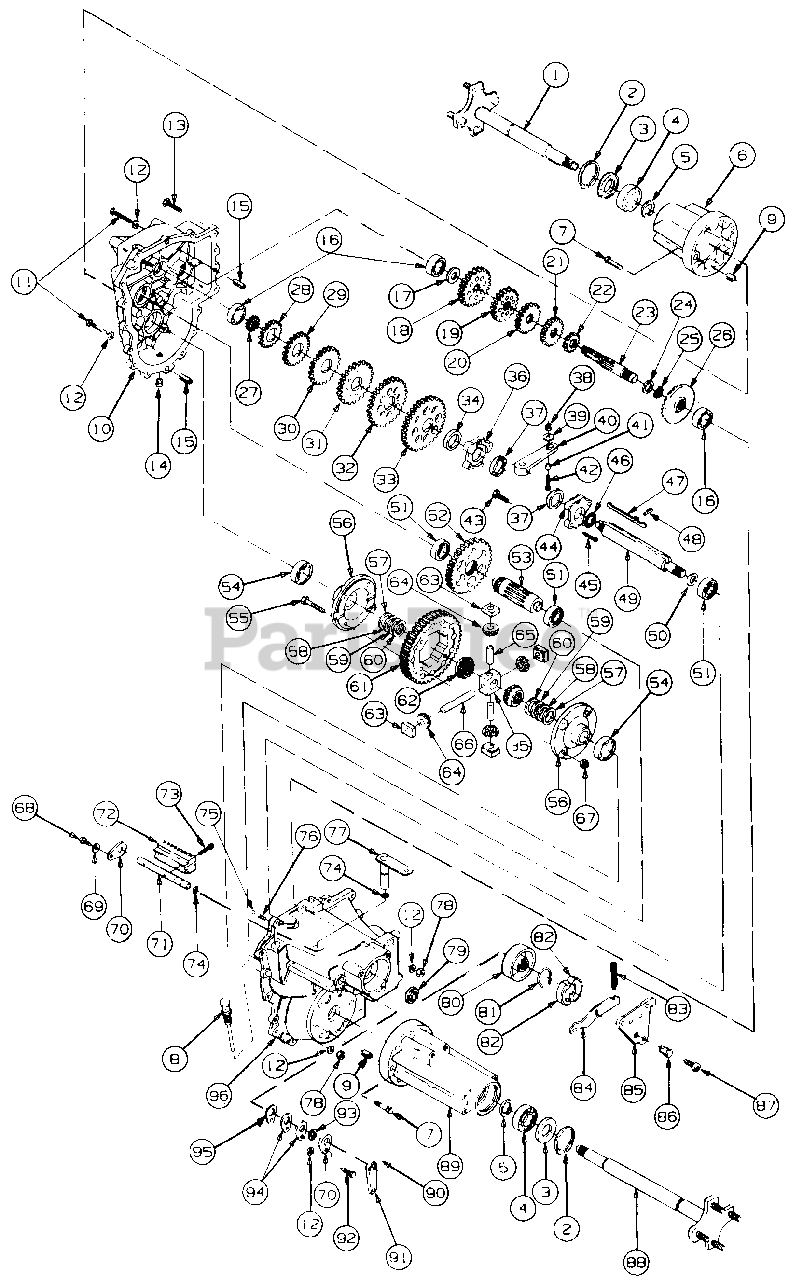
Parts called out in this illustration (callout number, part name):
1	Axle Assy, LH, 11.9" Lg
2	Ring, Inverted Retainer
3	Seal, Oil
4	Bearing
5	Ring, External Retaining
6	Housing, LH Axle
7	Crew, Hex L-Wash Tapp, 3/8-16 x 1.88
8	Dipstick, Oil
9	Bushing, Dowel
10	Housing, LH Differential
11	Screw, Hex Cap, 1/4-20 x 1.5
12	Washer, Flat, .25 x .62 x .052
13	Screw, Hex Wash Hd Tapp, 1/4-20 x 1.0
14	Plug, 1/2-14 NPTF
15	Pin, Slotted Spring, 7/16-1.0
16	Bearing, Ball
17	Washer, Flat, .68 x 1.25 x .060
18	Gear, 27T Drive, Sixth
19	Gear, 23T Drive, Fifth
20	Gear, 20T Drive, Fourth
21	Gear, 17T Drive, Third
22	Gear, 15T Drive, Second
23	Shaft, Drive w/First
24	Washer, Flat, .765 x 1.125 x .030
25	Washer, Wave, .79 x 1.125 x .012
26	Gear, 36T Bevel
27	Gear, 14T Reduction
28	Gear, 18T Shift, Sixth
29	Gear, 22T Shift, Fifth
30	Gear, 24T Shift, Fourth
31	Gear, 27T Shift, Third
32	Gear, 40T Shift, Second
33	Gear, 58T Shift, First
34	Spacer, Neutral
35	Block, Differential Pinion
36	Collar, Shift - LH
37	Spacer, Shift Key
38	Nut, Hex Center Lock, 5/16-18 GR5
39	Washer, Flat, .343 x .875 x .062
40	Arm, Key Shifter
41	Spacer, .316 ID x .44 OD x .263 Lg
42	Screw, Hex Cap, 5/16-18 x 1.0
43	Screw, Hex Cap, 5/16-18 x 1.25 GR5
44	Collar, Shift - RH
45	Screw, Socket Hd Cap, #10-32 x 1.25
46	Spring, Shift Key
47	Key, Shift
48	Pin, Dowel, 3/16 x 7/8 Lg
49	Shaft, Shift
50	Washer, Wave, .84 x 1.12 x .016
51	Bearing, Ball, .787 x 1.85 x .551
52	Gear, 44T Reduction
53	Shaft, 9T Output
54	Bearing, Ball
55	Screw, Hex Cap, 3/8-24 x 2.0
56	Cover, Differential
57	Washer, Flat, 1.0 x 1.56 x .010 Thk
58	Washer, Flat, 1.0 x 1.56 x .015 Thk
59	Washer, Flat, 1.0 x 1.56 x .020 Thk
60	Washer, Flat, 1.0 x 1.56 x .040 Thk
61	Gear, 60T Bull
62	Gear, 14T Differential Side
63	Block, Differential Thrust
64	Gear, 10T Differential Pinion
65	Shaft, Cross
66	Shaft, Cross, .50 OD x 3.485 Lg
67	Nut, Hex Lock, 3/8-24
68	Screw, Hex Wash Hd Tapp, 1/4-20 x .75
69	Washer, Bell, .265 x .75 x .062
70	Support, Interlock Shaft
71	Shaft, Interlock Shift
72	Interlock, Shift
73	Screw, Socket Hd Cap, 1/4-20 x 1.0
74	O-Ring, 1/2 ID x 5/8 OD
75	Ball, Detent, .250 Dia
76	Spring, Detent
77	Arm Assy, Shift
78	Nut, Hex Center Lock, 1/4-20
79	Seal, Shift Shaft
80	Drum, Brake
81	Spring, Brake
82	Shoe, Brake
83	Spring, Compression
84	Arm, Brake
85	Plate, Brake
86	Actuator, Brake Shoe
87	Screw, Low Hd Cap, 3/8-16 x .75
88	Axle Assy, RH, 15.6 Lg
89	Housing, Axle - RH
90	Pin, Spirol, 1/8 Dia x .812 Lg
91	Arm, Interlock Shift
92	Screw, Hex Wash Hd Tapp, 1/4-20 x .75
93	Ring, Retainer
94	Shim, Interlock Shaft Support, .030 Thk
95	Shim, Interlock Shaft Support, .015 Thk
96	Housing, RH Differential
